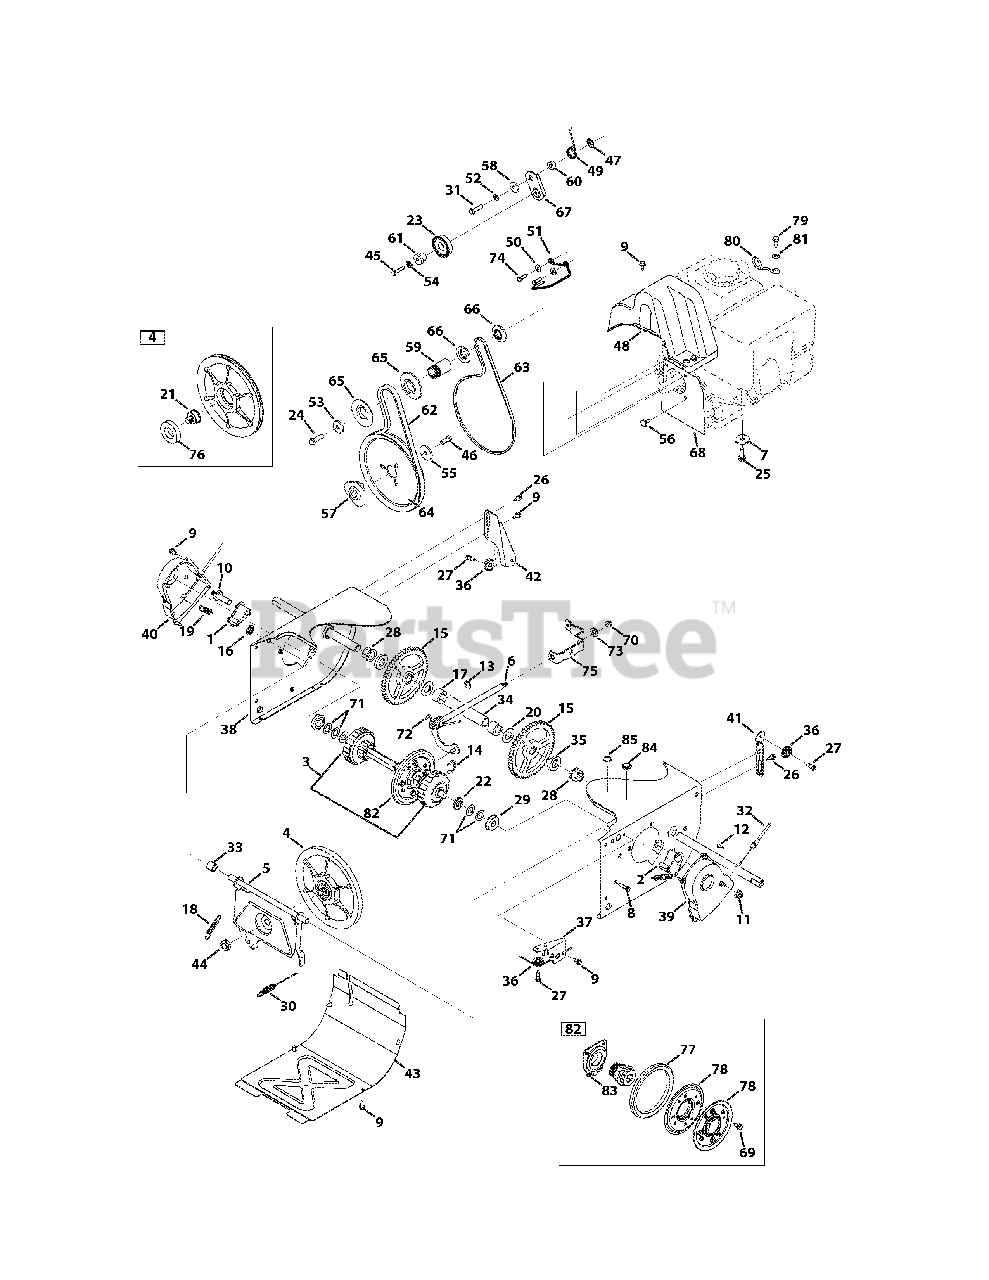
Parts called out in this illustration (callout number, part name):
1	Dogg Assembly, RH
2	Dogg Assembly, LH
3	Drive Shaft Assembly
4	Friction Wheel Disc Assembly
5	Friction Wheel Support
6	Rod Shift Assembly
7	Washer, Flat, .38 x 1.38
8	Screw, 1/4-20 x 1.000
9	Screw, 1/4-20 x .625
10	Actuator Shaft
11	Nut, Flangelock, 3/8-16
12	Hi-Pro Key, 3/16 x 3/4 DIA
14	Retainer Ring
16	Nut, Speed, .500
17	Spacer, .76 x .75
18	Extension Spring, .380 x 2.500
19	Extension Spring, .500 x 1.71
20	Washer, Flat, .76 x 1.49
21	Friction Pin, Disc Bearing
22	Spacer, .68 ID x 1.25 OD x .20
23	Pulley Assembly
24	Hex Head Screw, 3/8-24 x 1.25
25	Taptite Sems Screw, 3/8-16 x 1.000
26	Screw, Shoulder, .368 x .113 x 1/4-20
27	C Screw, Shoulder, .340 x .335 x 1/4-28
28	Hex Flange Bearing, .75 ID
29	Ball Bearing, 17 x 40 x 12
30	Drive Clutch Cable
31	Hex Head Screw, 5/16-24 x 1.25
32	Steering Cable
33	Spacer, .508 x .75
34	Axle Support Tube
35	Spacer, Axle
36	Roller Cable
37	Auger Cable Guide Bracket
38	Wheel Drive Frame (26" HD)
39	Shaft Retainer, LH
40	Shaft Retainer, RH
41	Auger Clutch Cable Guide Bracket
42	Drive Clutch Cable Guide Bracket
44	Nut, Flange, 5/8-18
45	Taptite Screw, 1/4-20 x 1.250
46	Hex Head Screw, 5/16-24 x .875
47	Nut, Push-On, .25 DIA
48	Belt Cover, 4-Way lrg. block
49	Spring, Torsion, .850 x .333
50	Washer, Flat, .349 x .879
52	Washer, Lock, 5/16
53	Washer, Flat, .45 x 1.5
54	Washer, Lock, 1/4
55	Washer, Flat, .34 x 1.50
56	Screw, Shoulder
57	Pulley Adapter, .75 DIA
58	Spacer, Shoulder, .3175 x .500
59	Spacer, .875 x 1.185
60	Spacer, .340 x .750
61	Spacer, Shoulder, .260 x .785
62	Auger Drive Belt, 4-Way lrg. block
63	V Belt, 3L x 36.64"
64	Auger Pulley, 8.1 x .5
65	Pulley, Half, 4L-V x 2.600
66	Pulley, Half, 3/8-V x 2.2
67	Drive Idler Bracket
68	Cover Plate, 4-Way lrg. block
69	Screw, 5/16-18 x .750
70	Nut, Flangelock, 5/16-18
71	Flat Washer, .67 x 1.174 x .02
72	Spring, Torsion, .750 x .968
73	Washer, Flat, .469 x .875 x .105
74	Hex Head Screw, 5/16-24 x 1.00
75	Speed Selector Shift Bracket
76	Ball Bearing, 30 x 55 x 13
77	Friction Wheel, 5.5 OD
78	Friction Wheel Plate
79	Hex Head Screw, 1.25 x 20
80	Cable Guide
81	Washer, Flat, .330 x .630
82	Friction Wheel Assembly
83	Bearing Assembly, Friction Wheel
84	Plug, 3/8 ID (26" HD)
85	Plug, 1/2 ID (26" HD)
